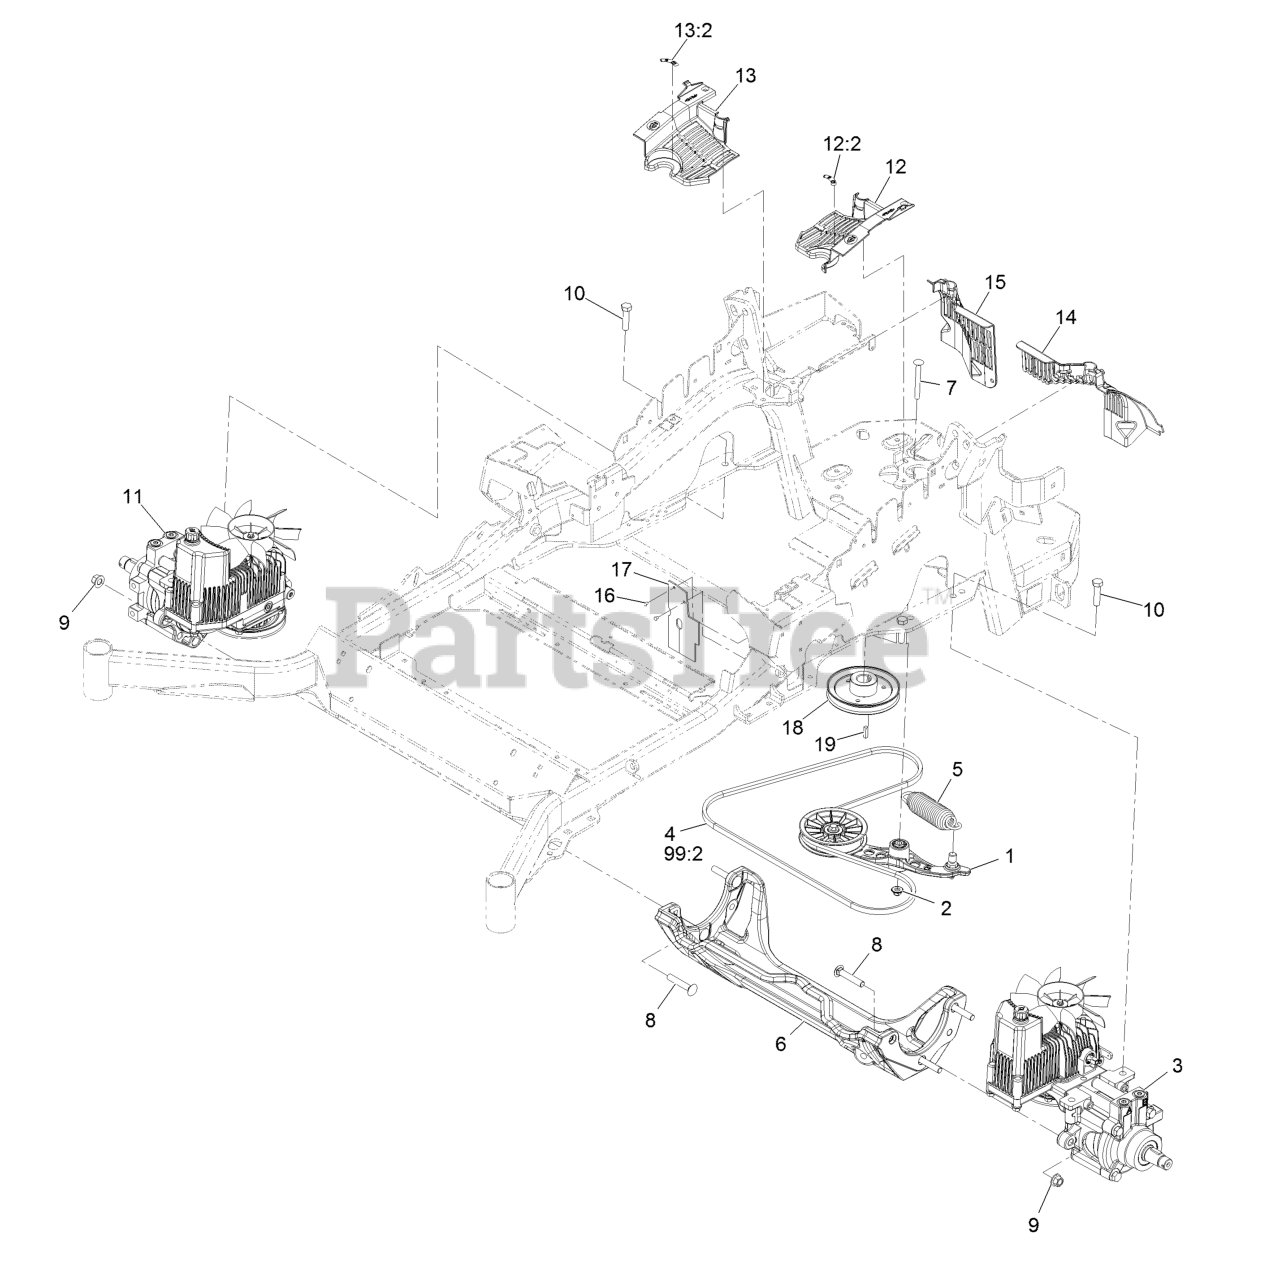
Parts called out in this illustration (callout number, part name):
1	Pump Idler ASM
2	Nut-Nyloc 3/8-16 Flg
3	LH Hydro ASM (16Cc W/ Shock)
4	Belt
5	Spring-Extension
6	Cradle-Hydro
7	Bolt-Carriage Shoulder 3/8-16 X 3 1/2
8	Screw-CARR
9	Nut-Lock 1/2-13
10	Screw-HH 1/2-13 X 1 1/4
11	RH Hydro ASM (16Cc W/ Shock)
12	LH Hydro Guard ASM
12:2	Decal-Oil, Hydro
13	RH Hydro Guard ASM
13:2	Decal-Oil, Hydro
14	Guard-Hydro Rear, LH Trim
15	Guard-Hydro, Rear (RH)
16	Rivet 3/16 X 1/4
17	Deflector-Air Flow
18	Sheave
19	Key-Machine 1/4 X 1/4 X 1
99	Bottle-Oil, 32Oz Hydraulic
99	Filter-Hydro
99	Bottle,Oil 1 Gallon Hydraulic
99	Kit, Hydro Service
99:1	Bottle-Oil, 32Oz Hydraulic
99:2	Belt
99:3	Filter-Hydro
